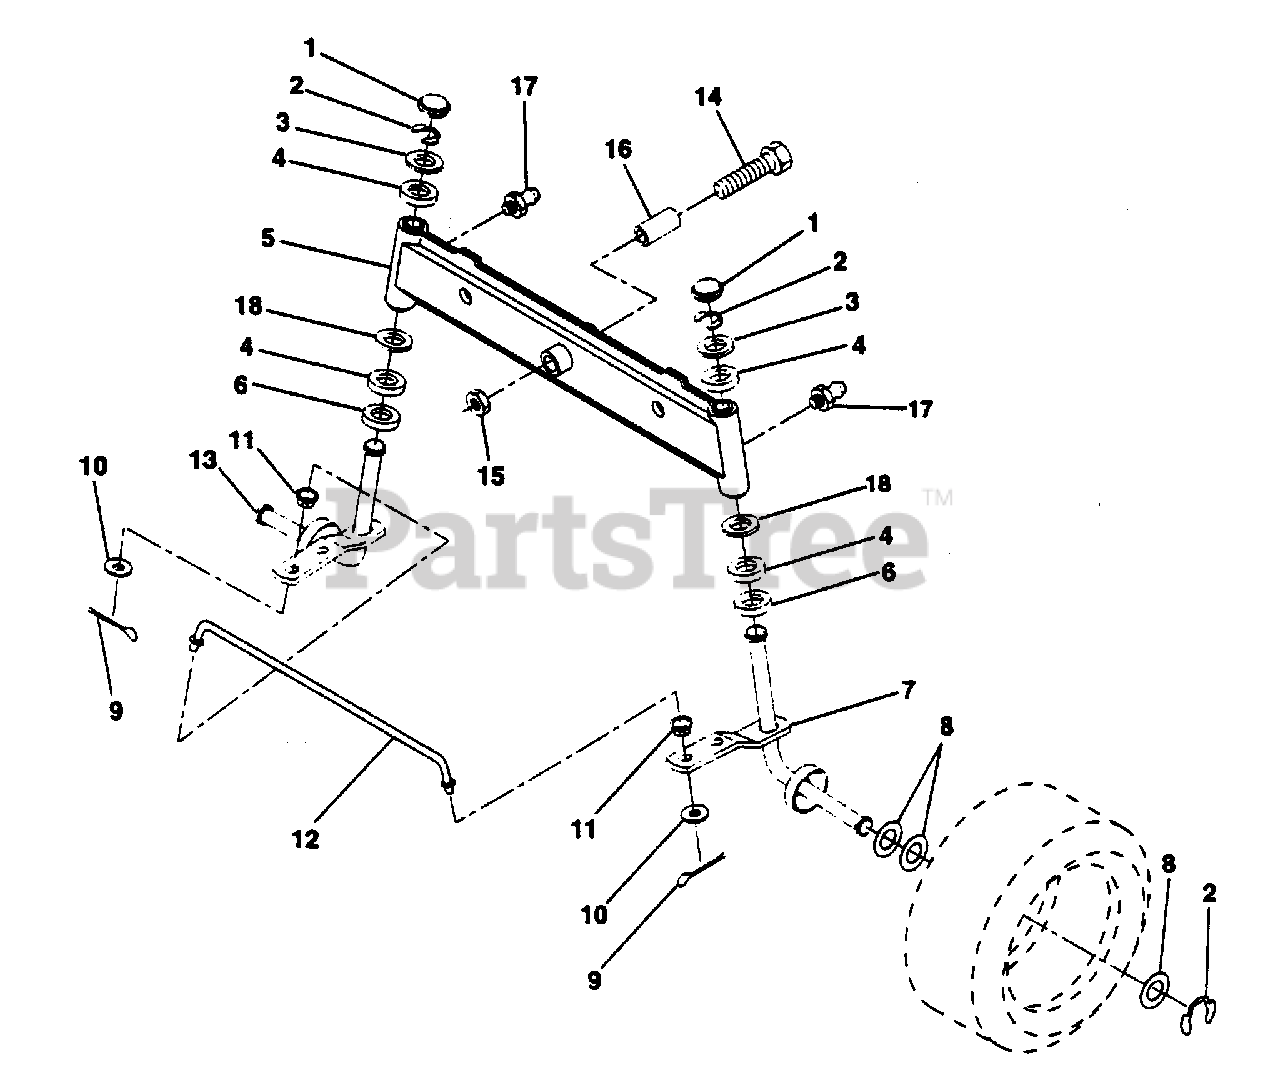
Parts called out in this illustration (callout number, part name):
3	Washer 25/32 x 1-5/8 x 16 Ga.
4	Nyliner
5	Axle, Front
6	Bearing, Thrust
7	Spindle, R.H. Asm.
8	Washer 25/32 x 1-1/4 x 16 Ga.
9	Pin, Cotter 1/8 x 3/4
10	Washer 13/32 x 13/16 x 16 Ga.
12	Rod, Tie
13	Spindle, L.H. Asm.
14	Bolt Hex 5/1-11 x 3-1/2
15	Nut, Lock Flange 5/8-11
16	Spacer, Bearing Axle
17	Fitting, Grease
18	Washer 27/32 x 1-1/4 x 16 Ga.
